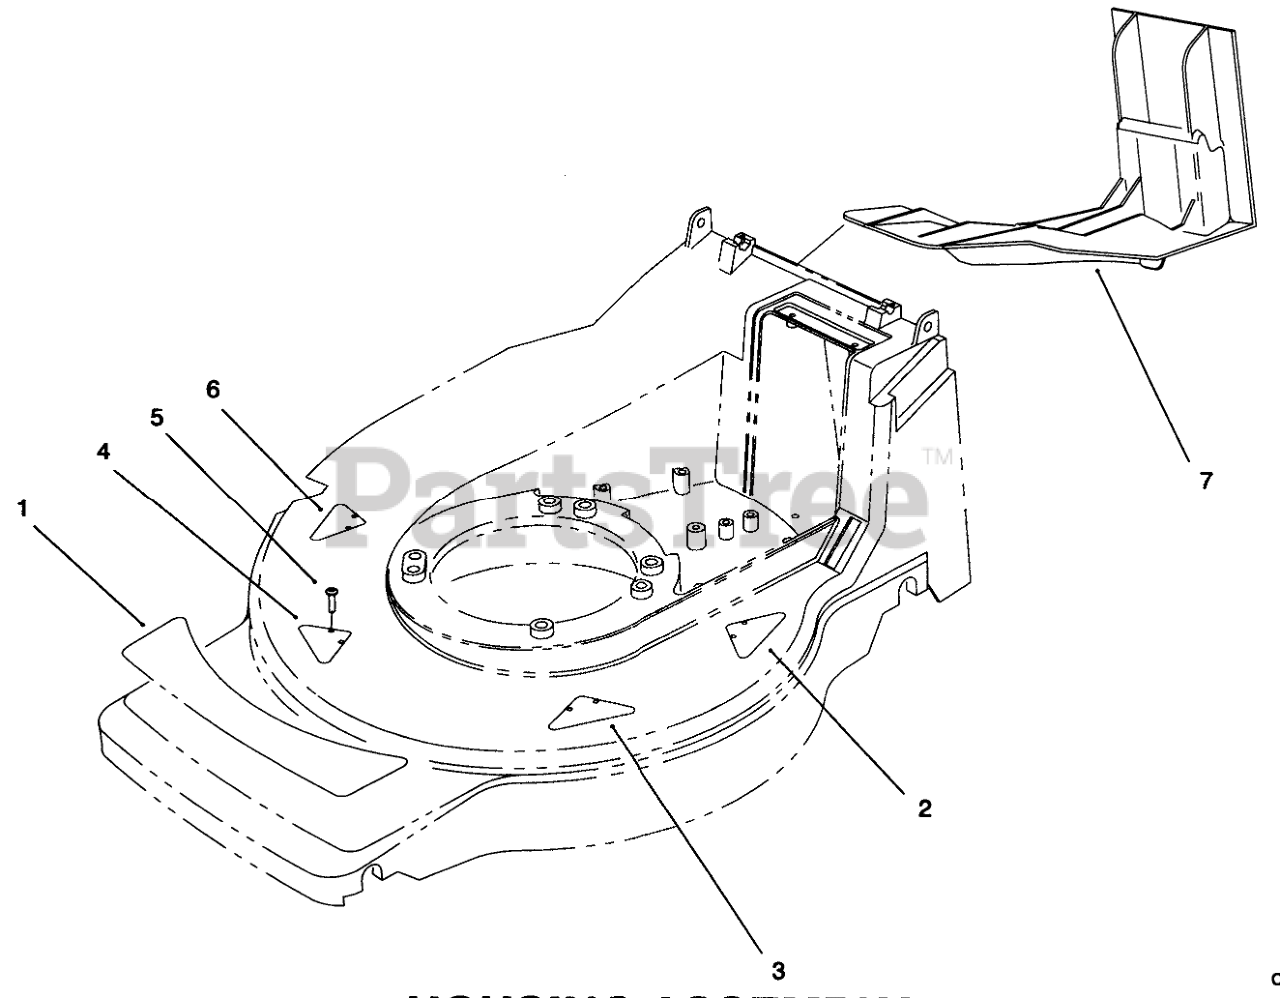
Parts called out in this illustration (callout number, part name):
1	DECAL - DECK
2	KICKER
3	KICKER
4	KICKER
5	SCREW-PPH
6	KICKER
7	DISCHARGE PLUG
